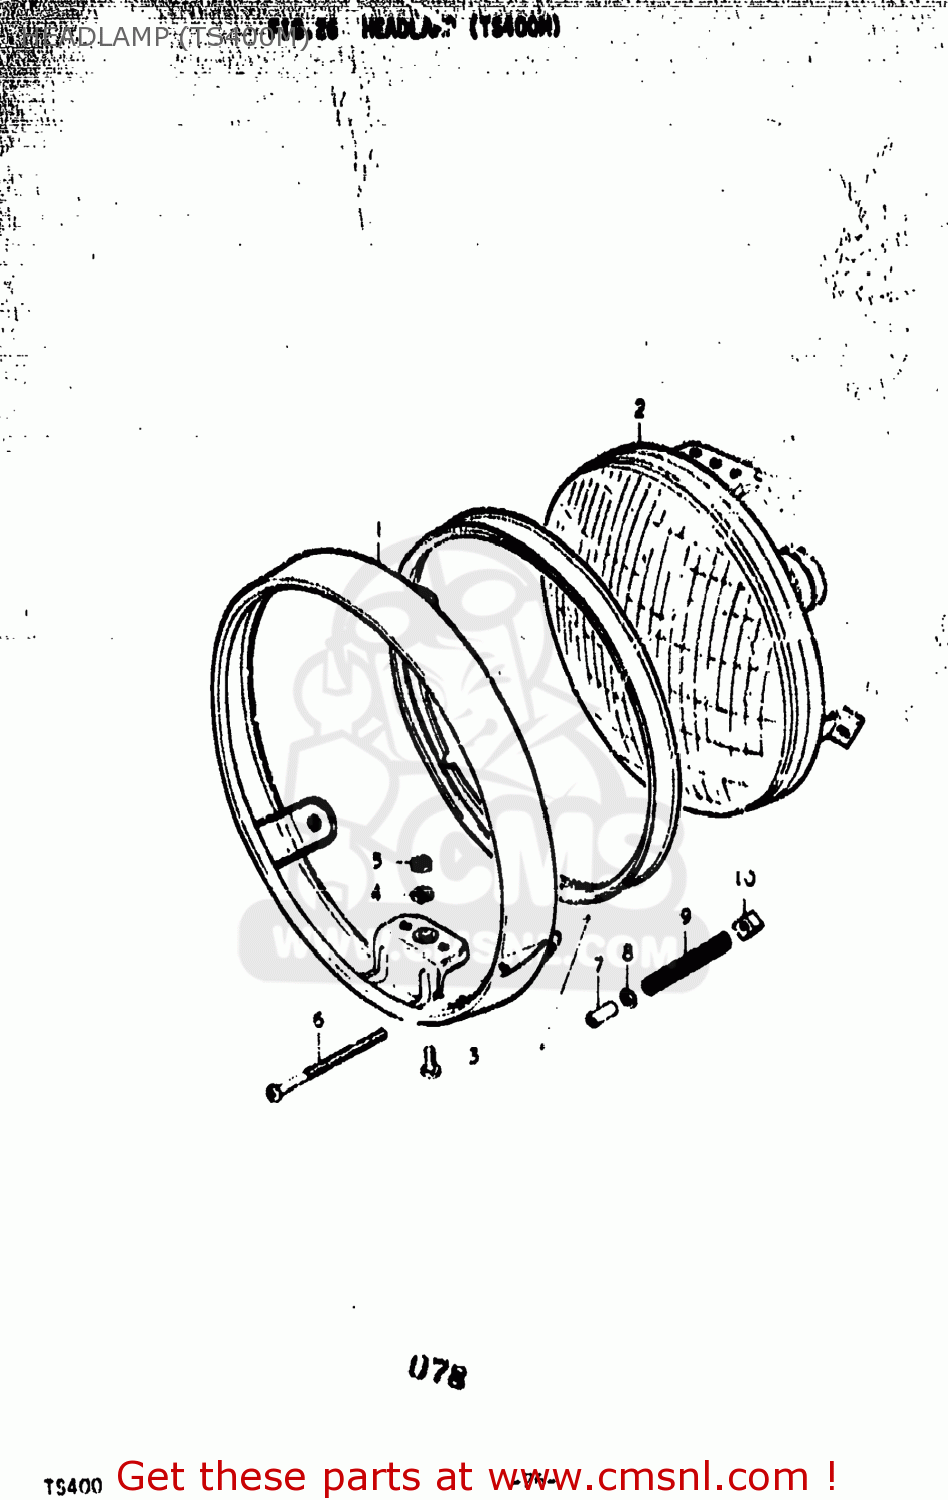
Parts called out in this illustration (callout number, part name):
1	RIM,HEADLAMP
2	LAMP UNIT
3	H/LAMP LENS UNIT FITING SCRE
4	LOCK WASHER
5	NUT
6	SCREW,HEADLAMP ADJUST
7	SPACER,HEADLAMP ADJUST
8	WASHER
9	SPRING,HEADLAMP ADJUST
10	NUT
